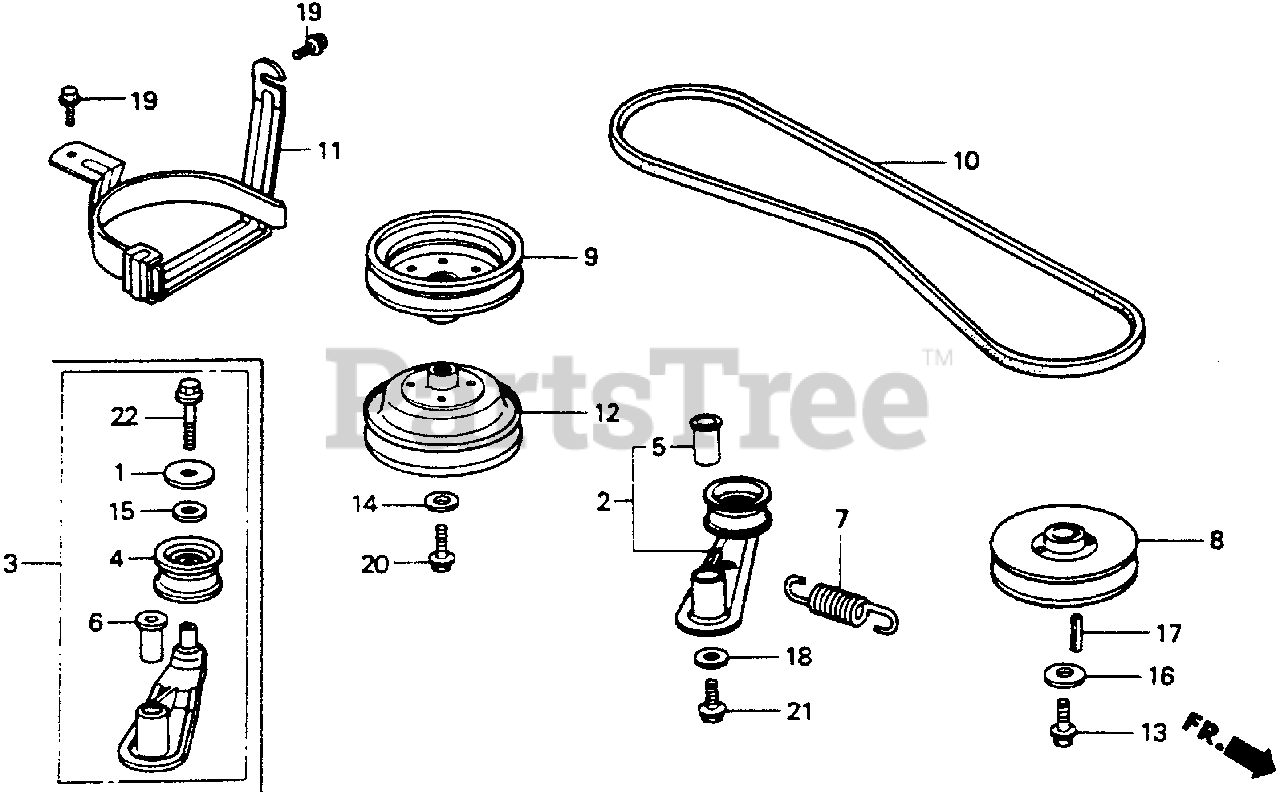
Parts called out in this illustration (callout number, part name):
2	ARM ASSY., TENSIONER
2	ARM, TENSION
6	BUSH (15X19X39.5)
7	SPRING, BELT TENSIONER
7	SPRING, PRIMARY BELT TENSION
8	PULLEY, ENGINE
8	PULLEY, ENGINE (120MM)
9	PULLEY, TRANSMISSION (130MM)
10	V-BELT, PRIMARY (SB-51)
11	STOPPER, BELT
12	PULLEY, TRANSMISSION (130MM)
13	BOLT, FLANGE (7/16"X28)
14	WASHER (8MM)
16	WASHER, PLAIN (12MM)
17	KEY (6.3X6.3X30)
18	WASHER, PLAIN (10.5X22X1.6)
19	BOLT, FLANGE (6X12)
20	BOLT, FLANGE (8X20)
21	BOLT, FLANGE (10X20)
